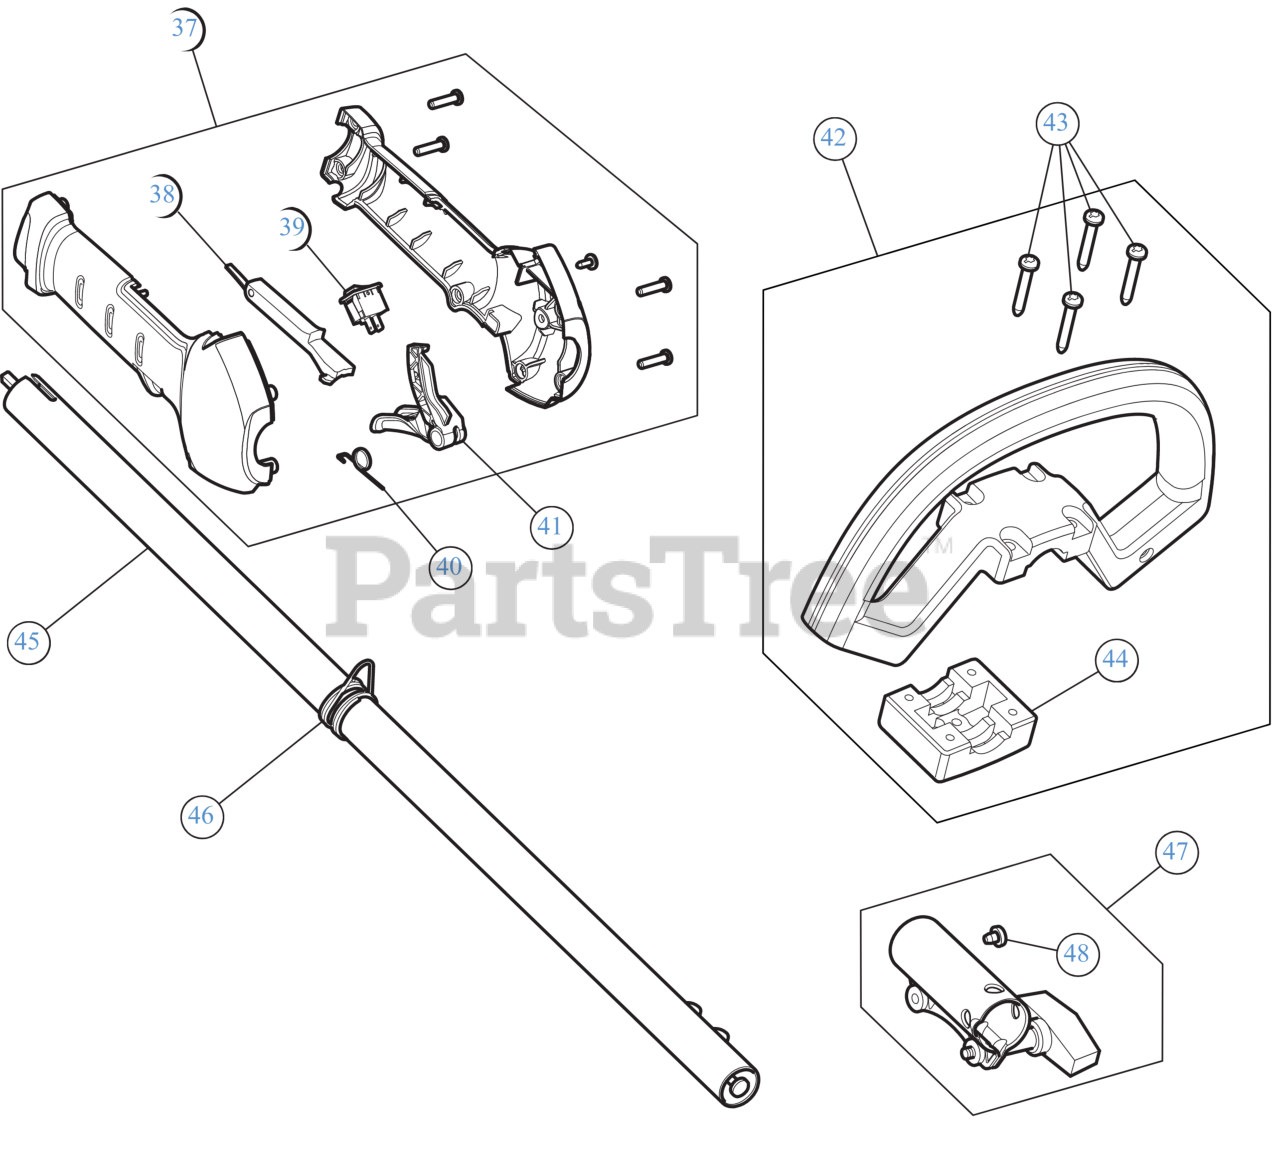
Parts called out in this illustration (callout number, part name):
37	THROTTLE HOUSING ASSEMBLY
38	LEVER LOCK OUT
39	SW, MOMENTARY ON/O
40	TRIGGER SPRING
41	THROTTLE TRIGGER
42	HANDLE:D
44	BASE-HANDLE LOOP:COM
45	BOOM ASSEMBLY UPR
46	CLAMP-SHOULDER STR
47	CLICK LINK
48	SCREW, 10-32X.250 TA
